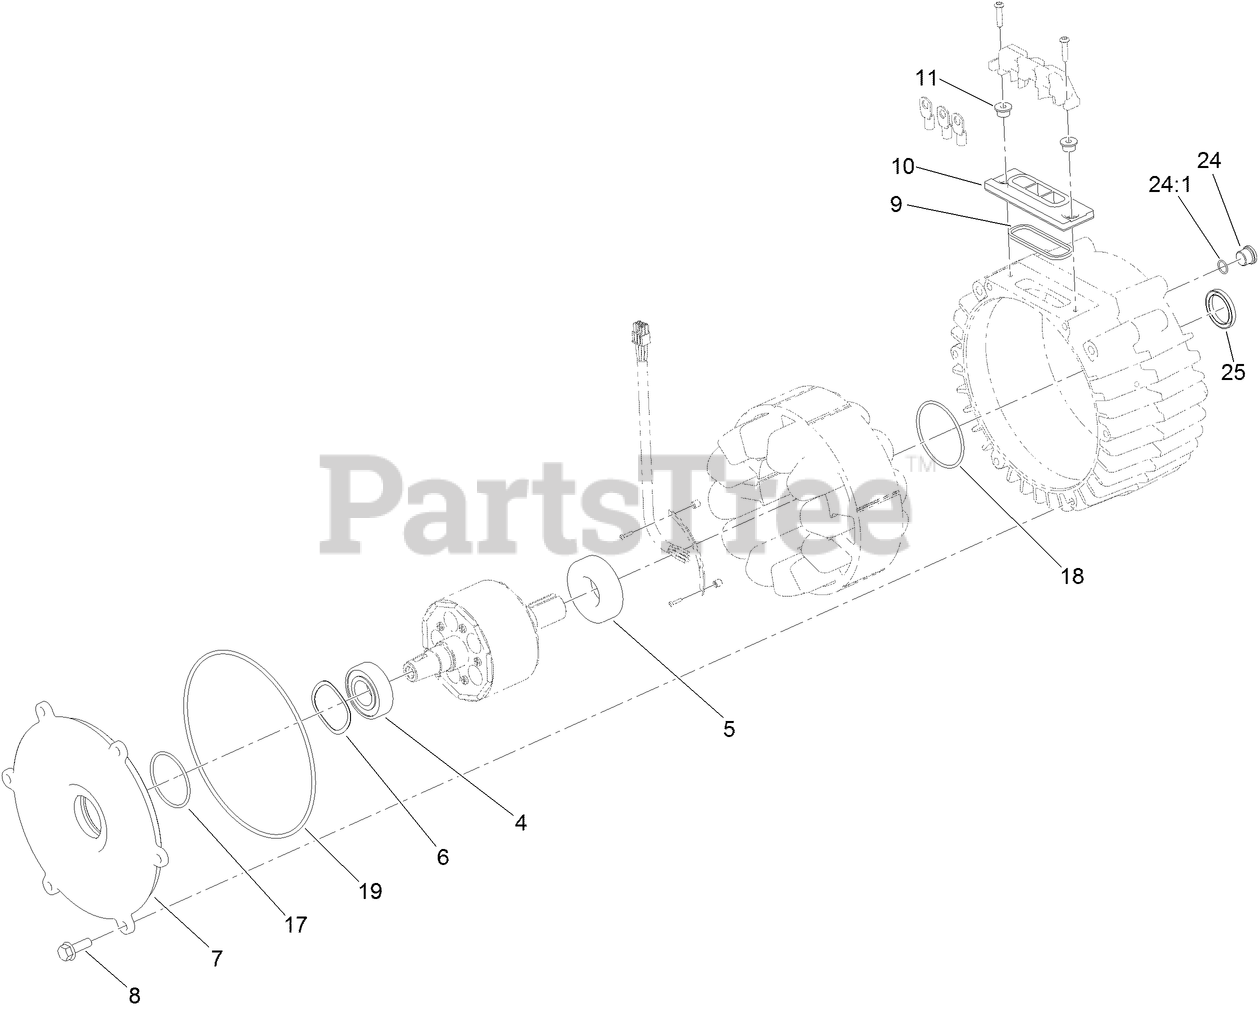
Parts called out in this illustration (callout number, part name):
4	Bearing
5	Bearing
6	Washer-Wave
7	Cover-Generator
8	SCREW-HHF
9	Gasket-Isolator
10	Isolator-Thermal
11	Spacer-Shoulder
24	PLUG-HEX, HOLLOW
24:1	O-RING
